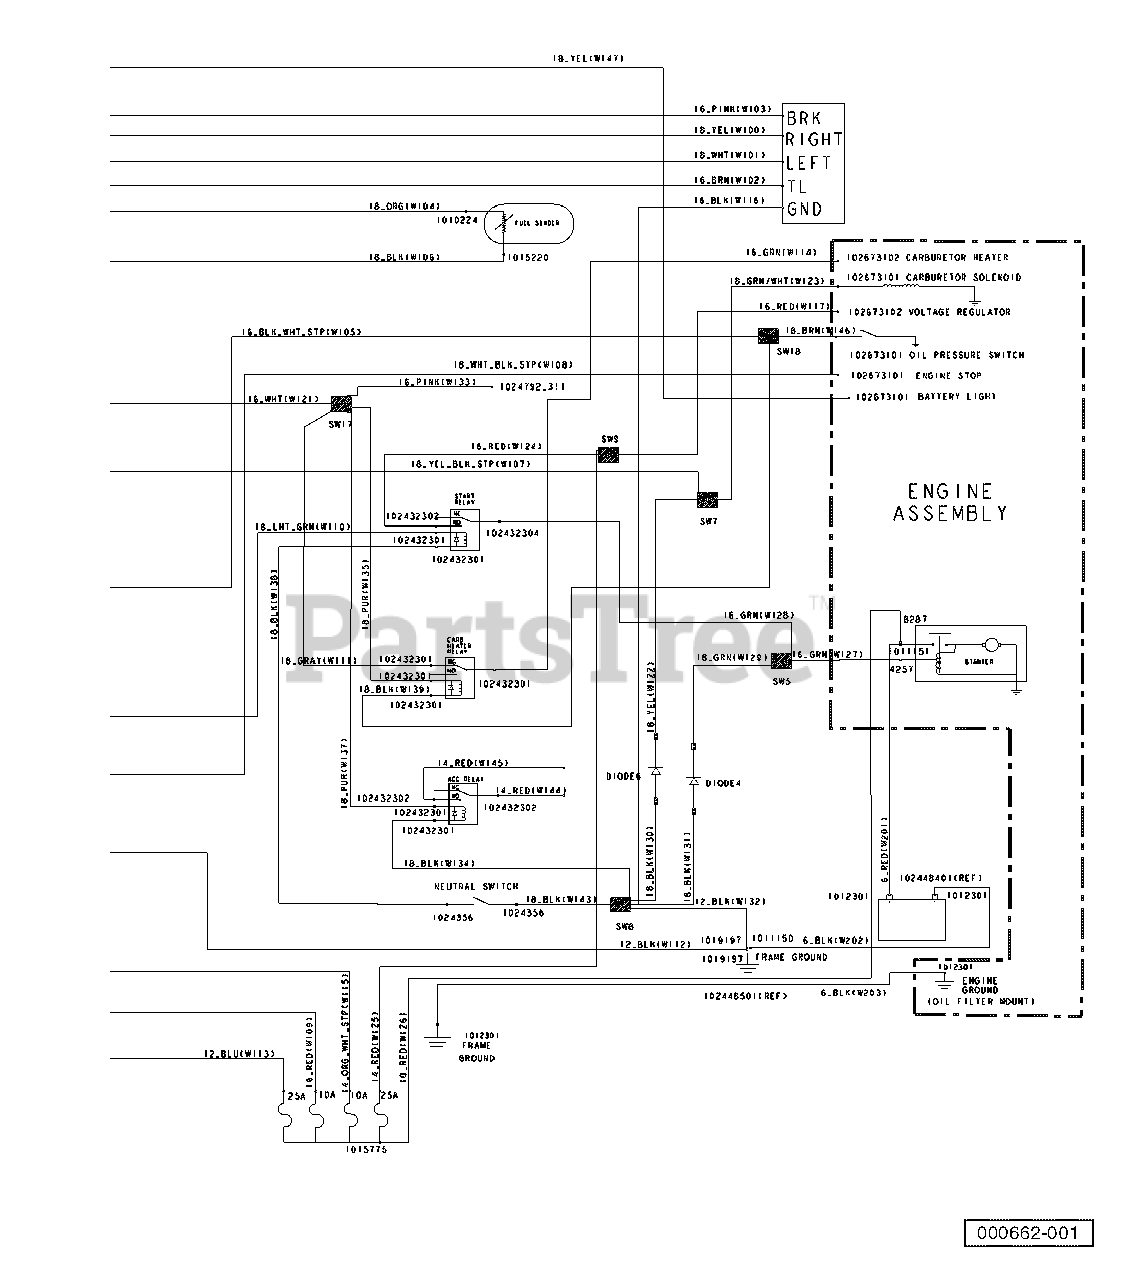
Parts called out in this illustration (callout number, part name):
1	Diode, General Purpose, 6.0a
2	Harness, AWD, Kawasaki
3	Asm, Switch, Limit, Awd
